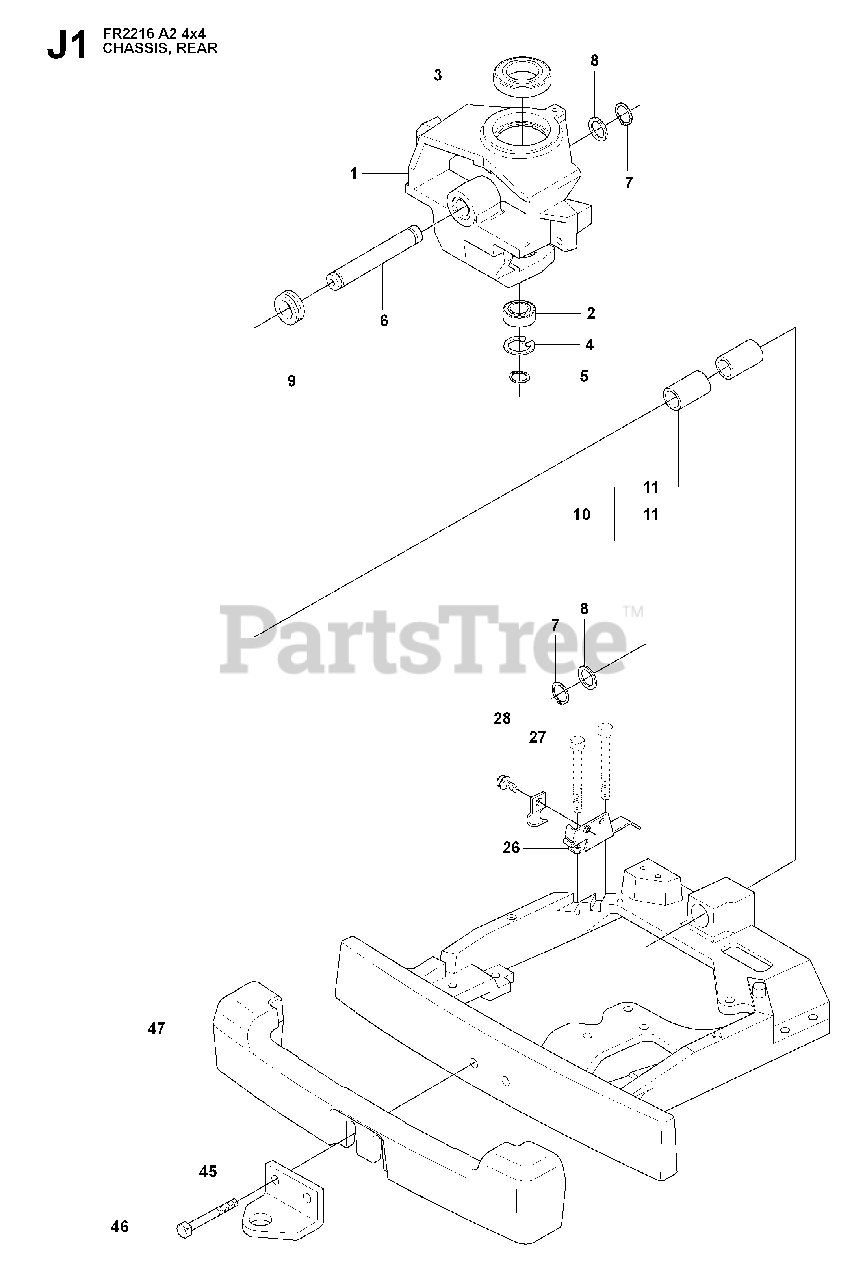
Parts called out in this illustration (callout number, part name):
2	BALL BEARING 6005-2RS
3	BALL BEARING 6010 2RS1
4	CIRCLIP SGH 47
5	RETAINING RING SGA 25
7	RETAINING RING SGA 25
45	DRAW RING
